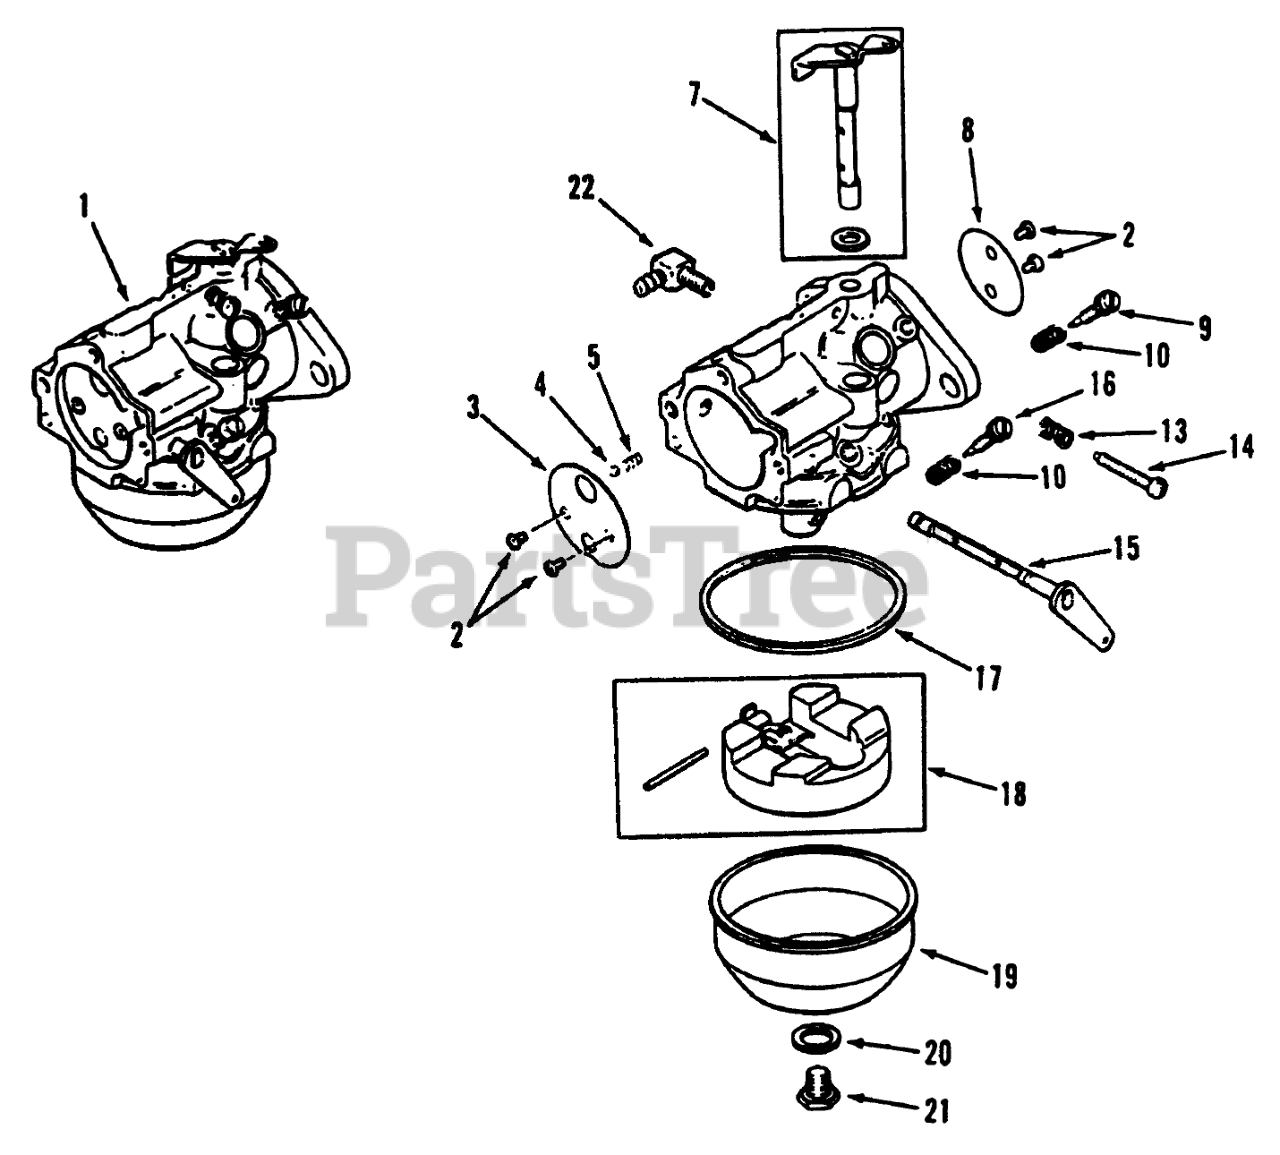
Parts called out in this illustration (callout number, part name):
1	Carburetor Assembly (Includes 5 thru 8)
2	Screw
3	Choke Plate
5	Spring
7	Shaft w/Lever & Seal
8	Plate-Throttle
9	Idle Fuel Adj. Needle
10	Spacer
13	Adj. Spring
14	Idle Speed Adj. Screw
15	Choke Shaft
16	Main-Needle
17	Gasket
18	Float Kit
19	Bowl-Fuel
20	Gasket
21	Screw
